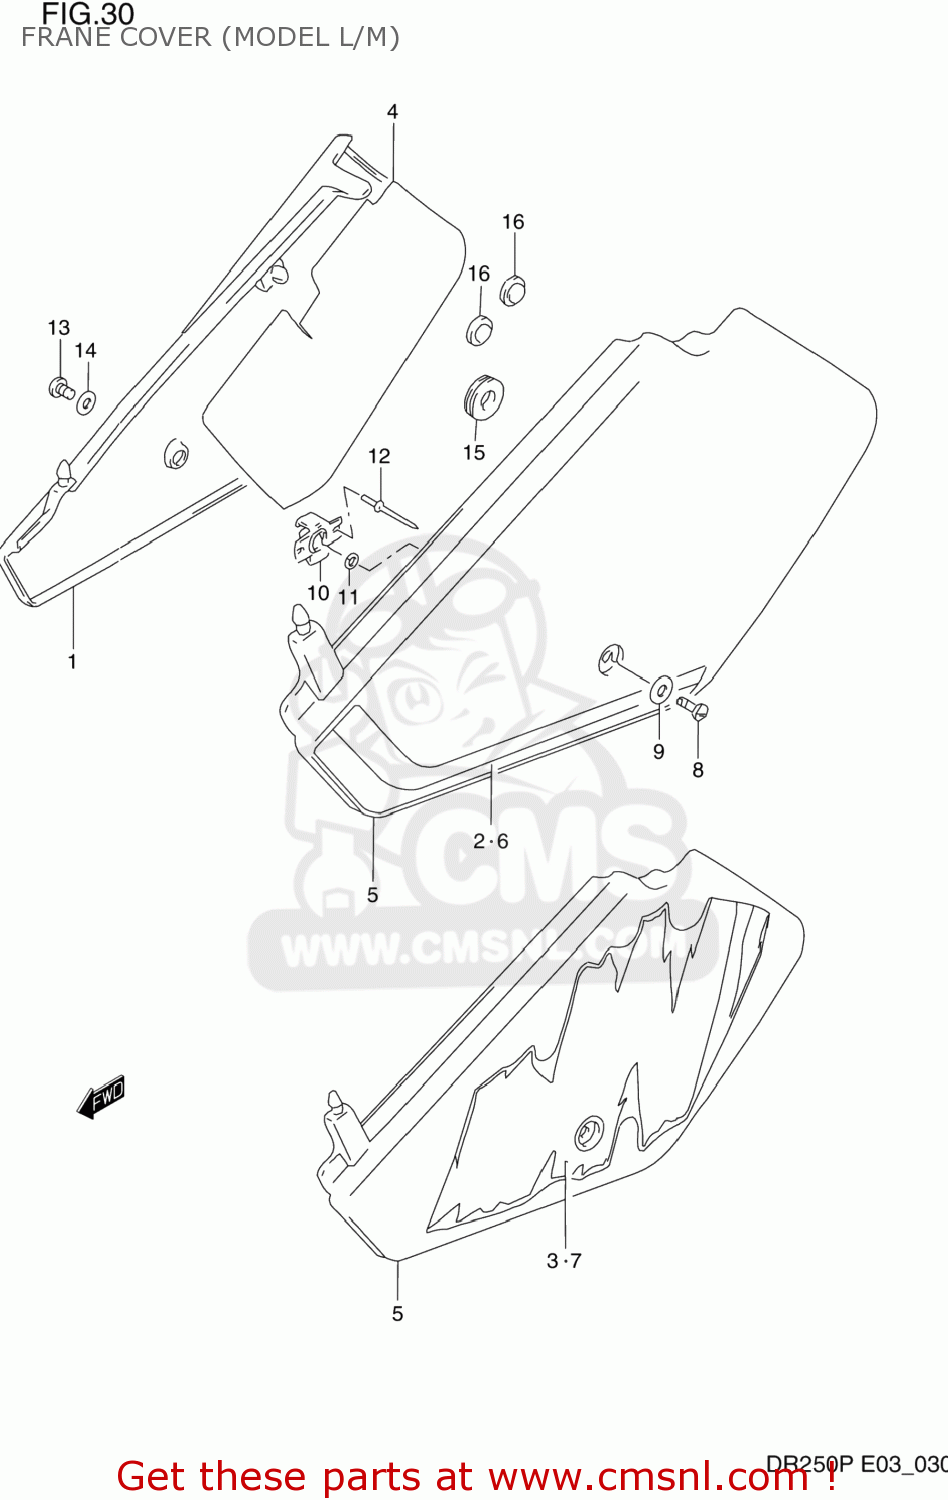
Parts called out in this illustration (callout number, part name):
1	COVER,FRAME,R(WHITE)
2	TAPE,FRAME COVER,RIGHT
3	TAPE,FRAME COVER,RIGHT
4	SHIELD,FRAME COVER,R
5	COVER,FRAME,L(WHITE)
6	TAPE,FRAME COVER,LEFT
7	TAPE,FRAME COVER,LEFT
8	STUD,FRAME COVER,LEFT
9	WASHER(7.2X18X1.6)
10	RETAINER,FRAME COVER STUD,L
11	PLATE,FITING
12	RIVET
13	SCREW
14	WASHER
15	CUSHION
16	CUSHION
